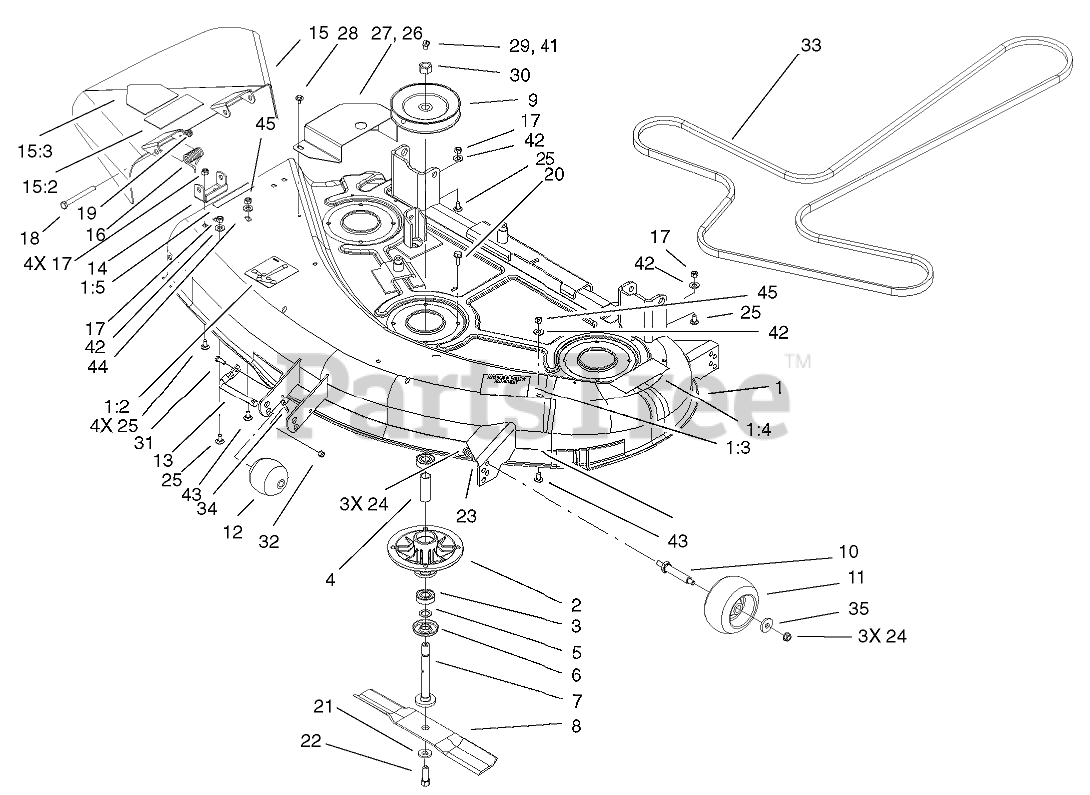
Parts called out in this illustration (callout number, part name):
1	44 INCH DECK ASM
1:2	DECAL-ROUTING, BELT
1:3	DECAL-ANTI SCALP
1:4	DECAL-DANGER
1:5	DECAL-DANGER
2	HOUSING-SPINDLE
3	BEARING-BALL
4	SPACER - BEARING
5	SPACER
6	SHIELD-BEARING
7	SHAFT-CENTER, SPINDLE
9	Pulley ASM
10	SPACER
11	WHEEL-GAGE
12	ROLLER
13	Shaft-Roller
14	BRACKET-PIVOT
15	DEFLECTOR ASM
15:2	DECAL-DANGER
15:3	DECAL-DANGER
16	SPRING
17	NUT-LOCK, NI
18	SCREW-HH
19	NUT-HEX
20	SCREW-TAPTITE
21	WASHER-BELLEVILLE
22	SCREW-HH
23	WASHER-BELLEVILLE
24	NUT-HHF, WHIZ
25	SCREW-CARR
26	Cover-Belt, LH
27	Cover-Belt, RH
28	SCREW-HHFTF
29	FITTING-GREASE
30	NUT-HEX
31	SCREW-HH
32	NUT-LOCK, NI
33	BELT V
34	PIN-COTTER
35	WASHER
41	FITTING-GREASE
42	WASHER-FLAT
43	SCREW-CARR
44	WASHER-FLAT
45	NUT-LOCK, NI
